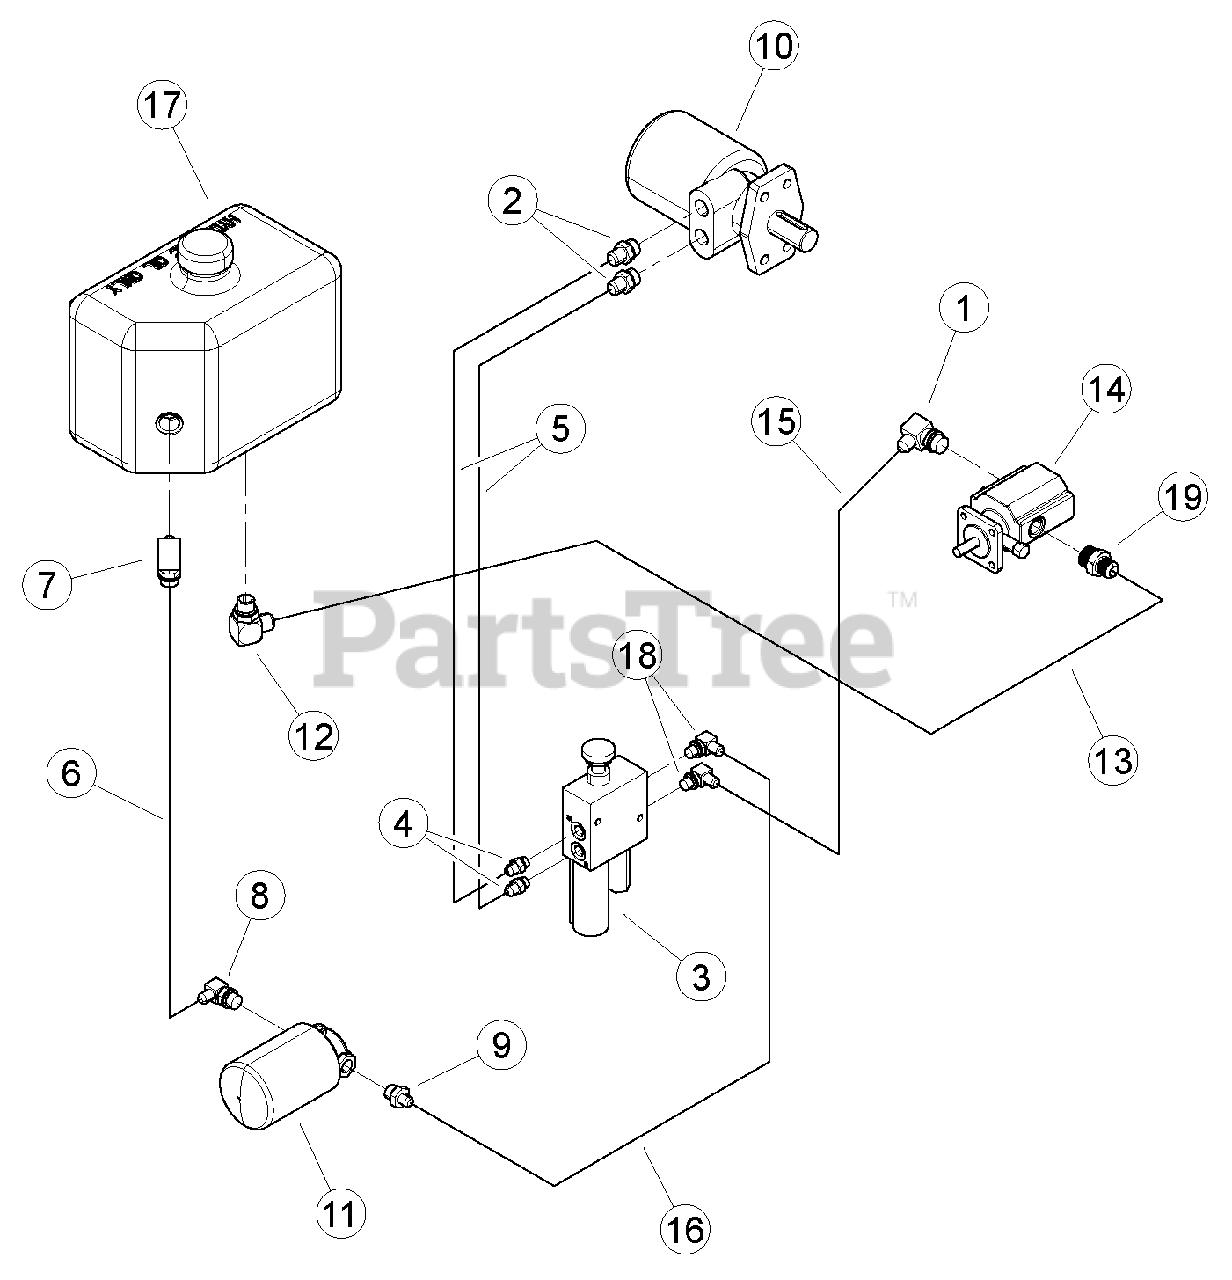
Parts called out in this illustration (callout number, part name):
1	ADAPTER, -10MORING/-8MJIC 90 DEG
2	ADAPTER, -10MORING/-8MJIC
3	VALVE, HYDRAULIC CONTROL
4	ADAPTER, -6MORING/-6MJIC
5	HOSE ASSEMBLY, -8FMJ/-6FMJ X 31
6	HOSE ASSEMBLY, -6FMJ/-6FMJ X 30
7	ADAPTER, -10MORING/-6MJIC 90
8	ADAPTER, -8MORING/-6MJIC 90 DEG
9	ADAPTER, -8MORING/-6MJIC
10	MOTOR, 45 CU IN HYDRAULIC
11	ASSEMBLY, HYDRAULIC FILTER
12	ADAPTER, -10MORING/-10MJIC 90 DEG
13	HOSE ASSEMBLY, -10FMJSW90/-10FMJ X 42
14	PUMP, 2 STAGE CW HI/LO 0.605 DISP.
15	HOSE, -8 FMJ/-6FMJ X 31" HYDRAULIC
16	HOSE, -6FMJIC/-6FMJIC X 24" HYDRAULIC
17	TANK, HYDRAULIC
18	ADAPTER, -6MORING/-6MJIC 90 DEG
19	ADAPTER, HYDRAULIC PUMP FITTING
